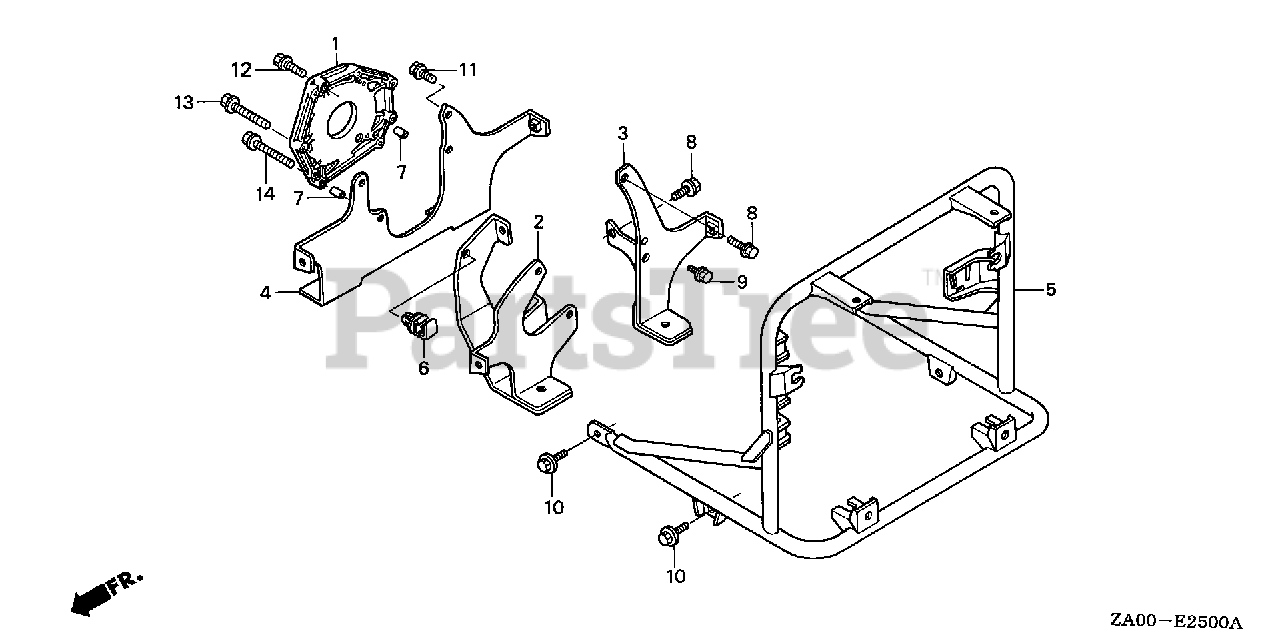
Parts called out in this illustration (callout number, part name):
2	STAY, R. FR. ENGINE MOUNTING
3	STAY, L. FR. ENGINE MOUNTING
4	STAY, R. RR. ENGINE MOUNTING
6	CLIP, WIRE HARNESS
8	BOLT, FLANGE (8X20)
9	BOLT, FLANGE (6X10)
10	BOLT, FLANGE (8X16)
11	BOLT, FLANGE (8X20)
12	BOLT, FLANGE (8X25)
